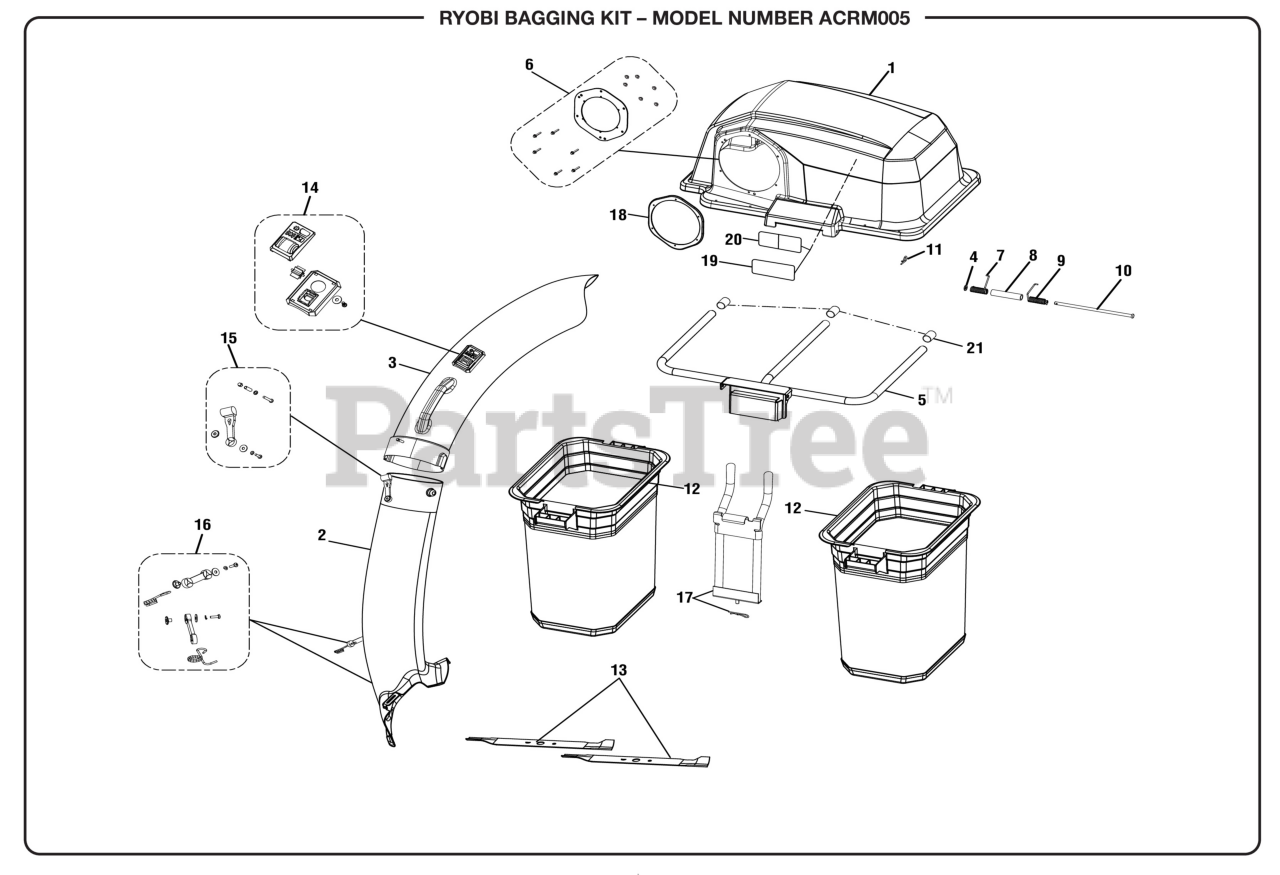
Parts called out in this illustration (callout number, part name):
1	Bagger Cover Assembly
2	Lower Bagger Tube Assembly
3	Upper Bagger Tube Assembly
5	Upper Frame Cover Assembly
7	Bagger Hinge Spring (Right)
8	Cover Hinge Bushing
9	Bagger Hinge Spring (Left)
10	Hinge Bagger Cover Pin
11	Bagger Hinge Pin Lock
12	Bagger Assembly Bag
13	Bagging Blade, 21 in., ZTR
14	Bagger Gauge Assembly
15	Upper Bungie Tube Connector Kit
16	Lower Bungie Tube Connector Kit
17	Bagger Assembly Lower Frame
18	Bagger Cover Bracket
19	Bagger Warning Label
20	Bagger Icon Warning Label
21	Hanger Cap
